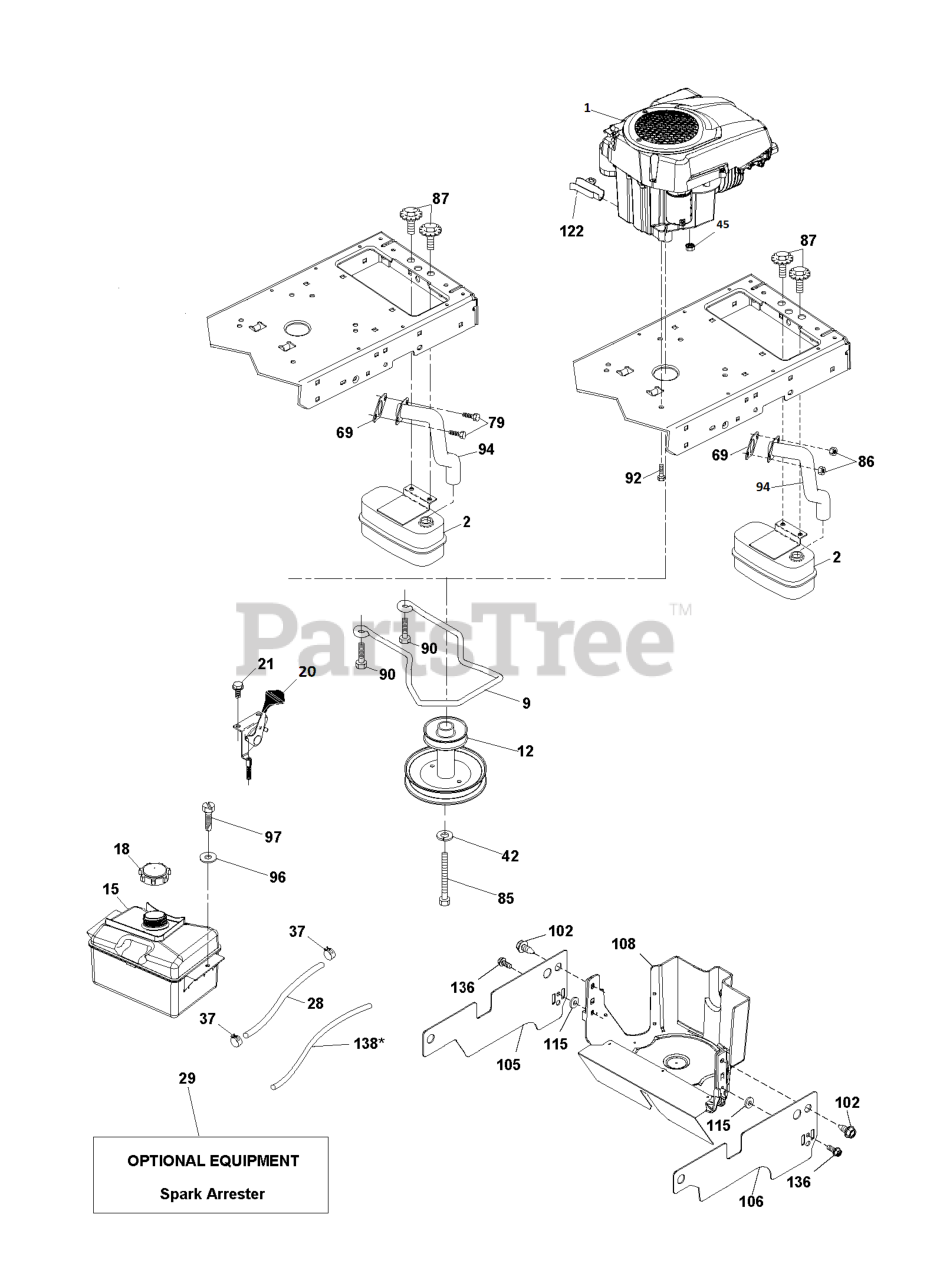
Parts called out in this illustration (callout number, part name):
1	ENGINE.LONCIN.SPARE/452
2	MUFFLER.ASM.SINGLE
12	ENGINE.PULLEY
15	FUEL TANK
15	FUEL.TANK.ASM.NON-EPA
18	CAP.2.25'.VENTED.RATCHET.EPA
20	CONTROL.TH/CK.C.BLACK
28	HOSE 1/4" LOW PERMEATION FUEL
29	KIT.SPARK ARRESTOR 794945 B&S
37	HOSE CLAMP
45	NUT HEXAGON WITH FLANGE, SERRA
69	GASKET GASKET.EXHAUST.LONCIN 3
79	Screws
85	BOLT.HEX.7/16-20X4.GR5.1.5BLUE
86	NUT.HEX.FLANGE.TOPLOCK
87	BOLT.5/16-18UNCX3/4 W/SEMS.BLK
90	SCREW 3/8-16X1
92	SCREW 3/8-16X1
94	TUBE TUBE.EXHAUST.LONCIN 452.T
97	SCREW HEXWSHR 1/4-20X3/4
102	BOLT.HEX.HD.WASHER.5/16-18X.75
105	SHIELD.SIDE.LH.3842"TEX FRN.BK
106	SHIELD.SIDE.LH.3842"TEX FRN.BK
108	COVER ENGINE PULLEY COVER WITH
115	RETAINER
122	EXTENSION DRAIN OIL
136	Screws
